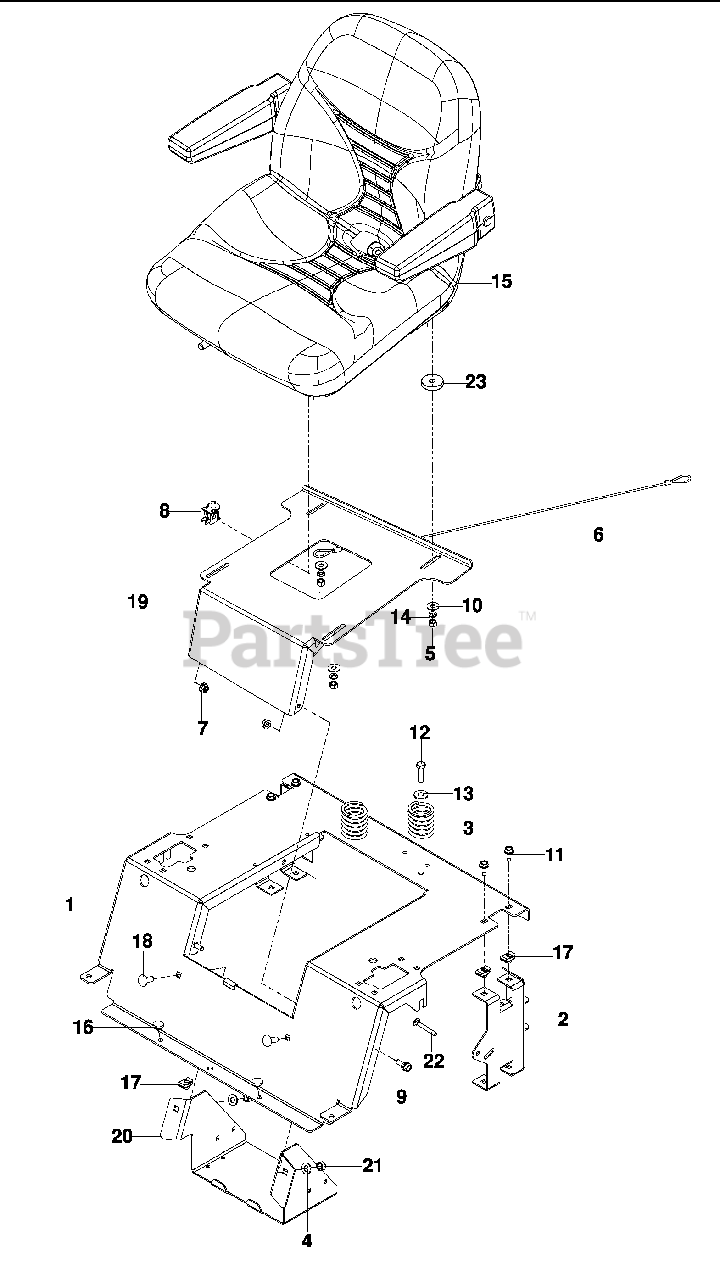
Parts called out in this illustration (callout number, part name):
1	SUPPORT, SEAT
2	SUPPORT, REAR SEAT
3	SPRING, SEAT
4	WASHER 3/8 SAE FLAT
5	NUT 5/16-18 HEX NYLOC
6	LANYARD, SEAT
7	NUT 5/16-18 FLANGE NYLOC
8	SWITCH, SEAT
9	BOLT 5/16-18 HEX HD SHLDR
10	WASHER 5/16 STD FLAT
11	BOLT 5/16-18 x ¾ THD FRM
12	HCS 3/8-16 x 1¼
13	WASHER 3/8 FLAT STD
14	WASHER 5/16 SLW
15	SEAT
16	GROMMET, BUMPER
17	RETAINER, U TYPE
18	RHSNB 3/8-16 x 1
20	BOX, BATTERY
21	NUT 3/8-16 HEX NYLOC
22	RHSNB 5/16-18 x 2½
23	WASHER, NYLON
